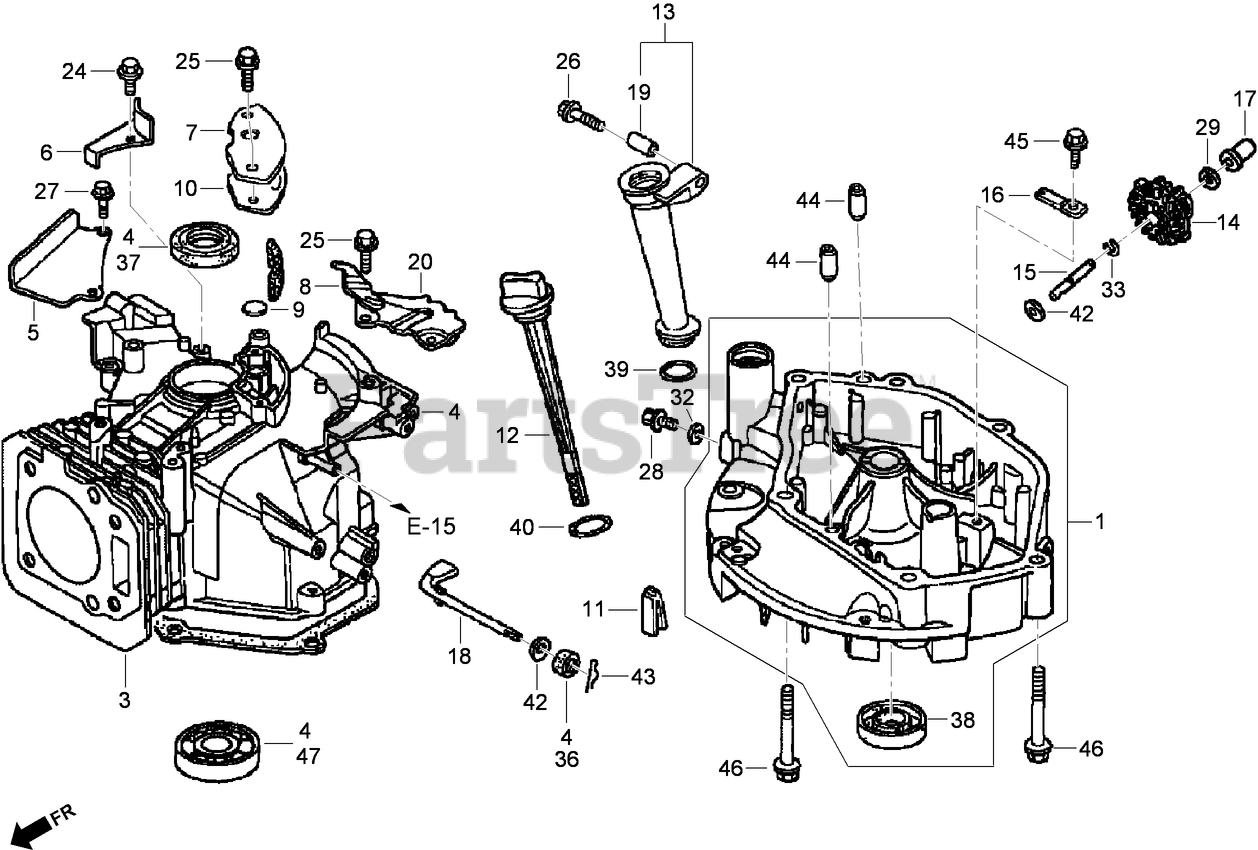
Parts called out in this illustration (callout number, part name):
1	OIL PAN ASM
3	GASKET-PAN, OIL
4	CYLINDER ASM
5	PLATE-GUIDE
6	PLATE-GUIDE (A)
7	COVER-BREATHER
8	Filter-Breather
9	VALVE-BREATHER
10	GASKET-COVER, BREATHER
11	RUBBER-RETURN, OIL
12	Dipstick-Oil
13	EXTENSION-FILLER, OIL (106 mm)
14	GOVERNOR ASM
15	SHAFT-HOLDER, GOVERNOR
16	Plate-HOLDER, Governor Shaft
17	SLIDER-GOVERNOR
18	SHAFT-ARM, GOVERNOR
19	Collar-Extension
20	STAY-TANK
24	BOLT-FLANGE (6X12) (C T200)
25	BOLT-FLANGE (6X14) (C T200)
26	Bolt-Flange (6X32)
27	BOLT-FLANGE (6X20) (C T200) (engine serial numbers up to 6702082)
28	Bolt-PLUG, Drain
29	WASHER-THRUST (6MM)
32	WASHER-PLUG, DRAIN (102MM)
33	CLIP-HOLDER, GOVERNOR
36	SEAL-OIL (6X11X4)
37	SEAL-OIL (25X38X7)
38	SEAL-OIL (25.4X40X7)
39	O-RING (22.1X2.2)
40	O-RING (25.5X3)
42	WASHER-PLAIN (6MM)
43	PIN-LOCK (8MM)
44	Pin-Dowel (8X14)
45	Bolt-Flange (6X12)
46	BOLT-FLANGE (8X50)
47	BEARING-BALL, RADIAL (6205)
